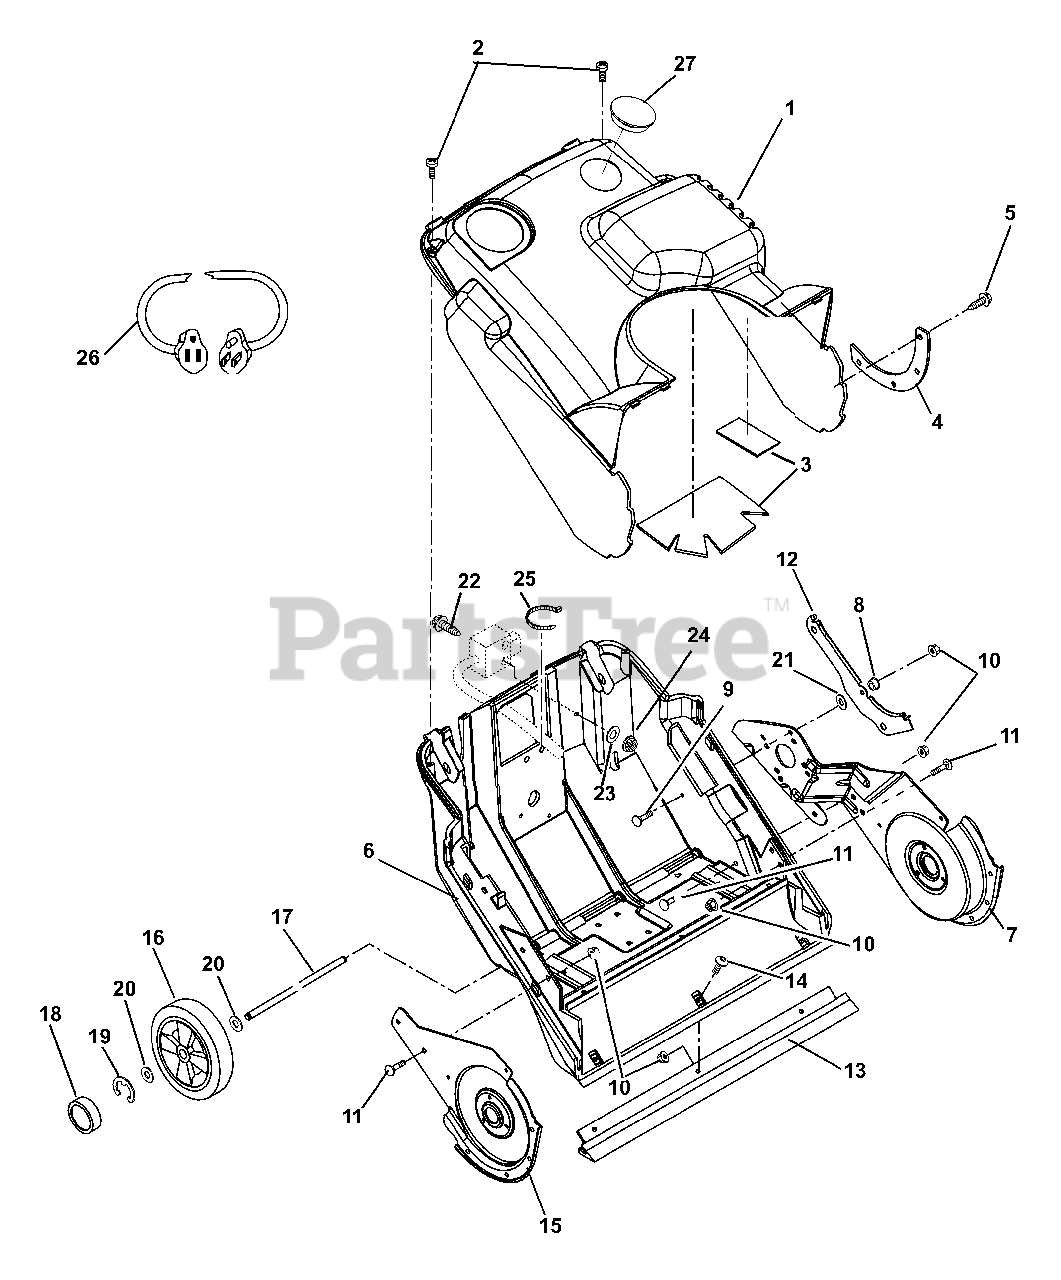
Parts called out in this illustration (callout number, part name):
1	COWL ASSY-REPLACEMENT
2	SCR-SPEC-TAP #10X1.0
3	SHEET-HEAT REFLECTIVE
4	PLATE-COWL RETAINER
5	SCR-TAP POINTED HWH BLACK12-24
6	CHASSIS
7	SUPPORT-BRG,LH
8	BSHG-FLG .265X.437X.250X.750
9	@BLT-RDHDSQNK .25-20X1.00 G5YZ
10	NUT-LK-FLG .250-20 PL BLK
11	@BLT-RDHDSQNK .25-20X.75 G5YZ
12	GUIDE-CABLE
13	SCRAPER BLADE, UHMW-PE
14	SCR-MCH .25-20X.75 TXTR YWZC
15	SUPPORT-BRG,RH
16	T/WHL ASSY 7.0X1.5
18	CAP-HUB
19	RG-RTNG-EXT .375X.035 TYP E
20	@WSHR-FL-STL.406X.812X.065 YWZ
21	@WSHR-FL-STL.312X.734X.065 YWZ
22	@SCR-MCH 8-32X2.75 HWH YWZC
23	@WSHR-FL-STL.219X.50X.049 YWZC
24	@NUT-LK-NYL 8-32 W/INSTR YWZC
25	CABLE TIE LG 5-1/2
26	CORD, ELECTRIC START CORD 120V
27	PLUG, DOME-BLACK,4.0" DIA
